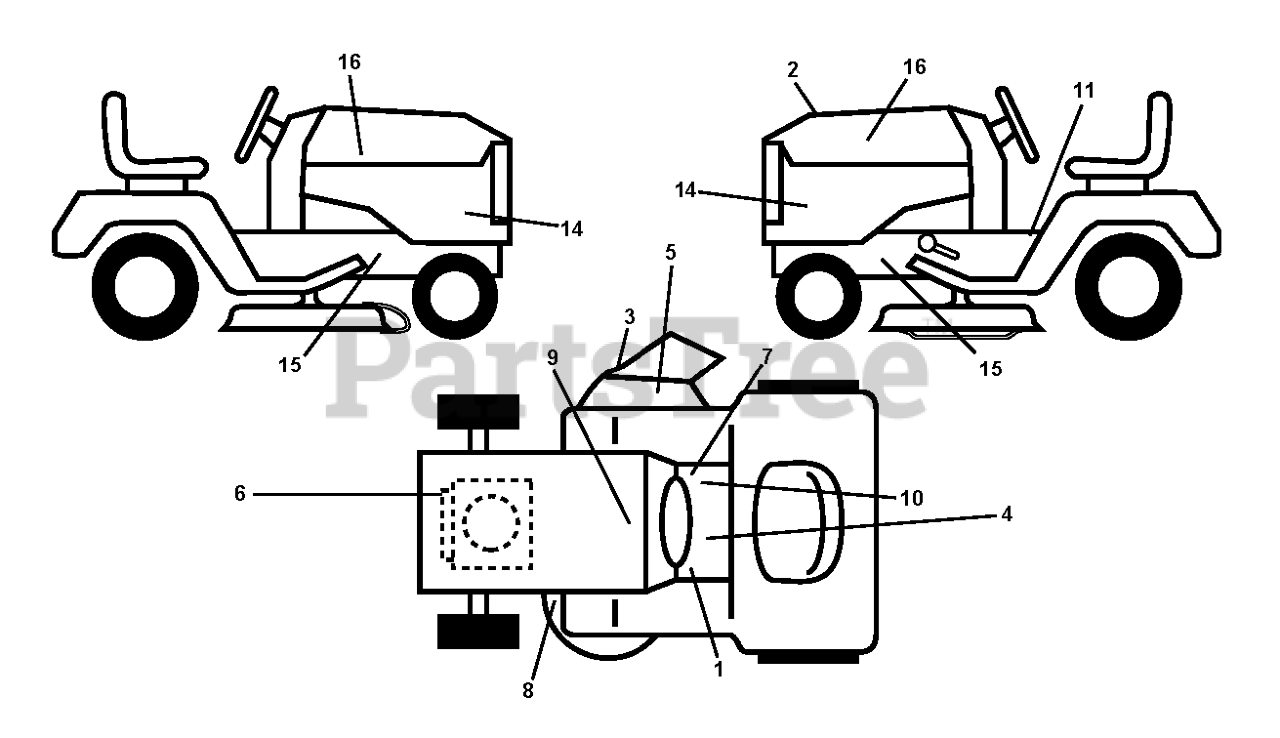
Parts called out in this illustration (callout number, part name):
1	DECAL
3	DECAL, DEFLECT WARNING
4	Decal, Fender 100 DB/CE
5	DECAL.INTERNATIONL.CUTFINGER
6	DECAL
7	DECAL PARK BRAKE
8	DECAL V BELT SCHEMATIC
9	DECAL BTRY SYMBOLS
10	DECAL
11	LABEL
16	DECAL.HOOD.LOGO.ORANGE.HUSQVAR
